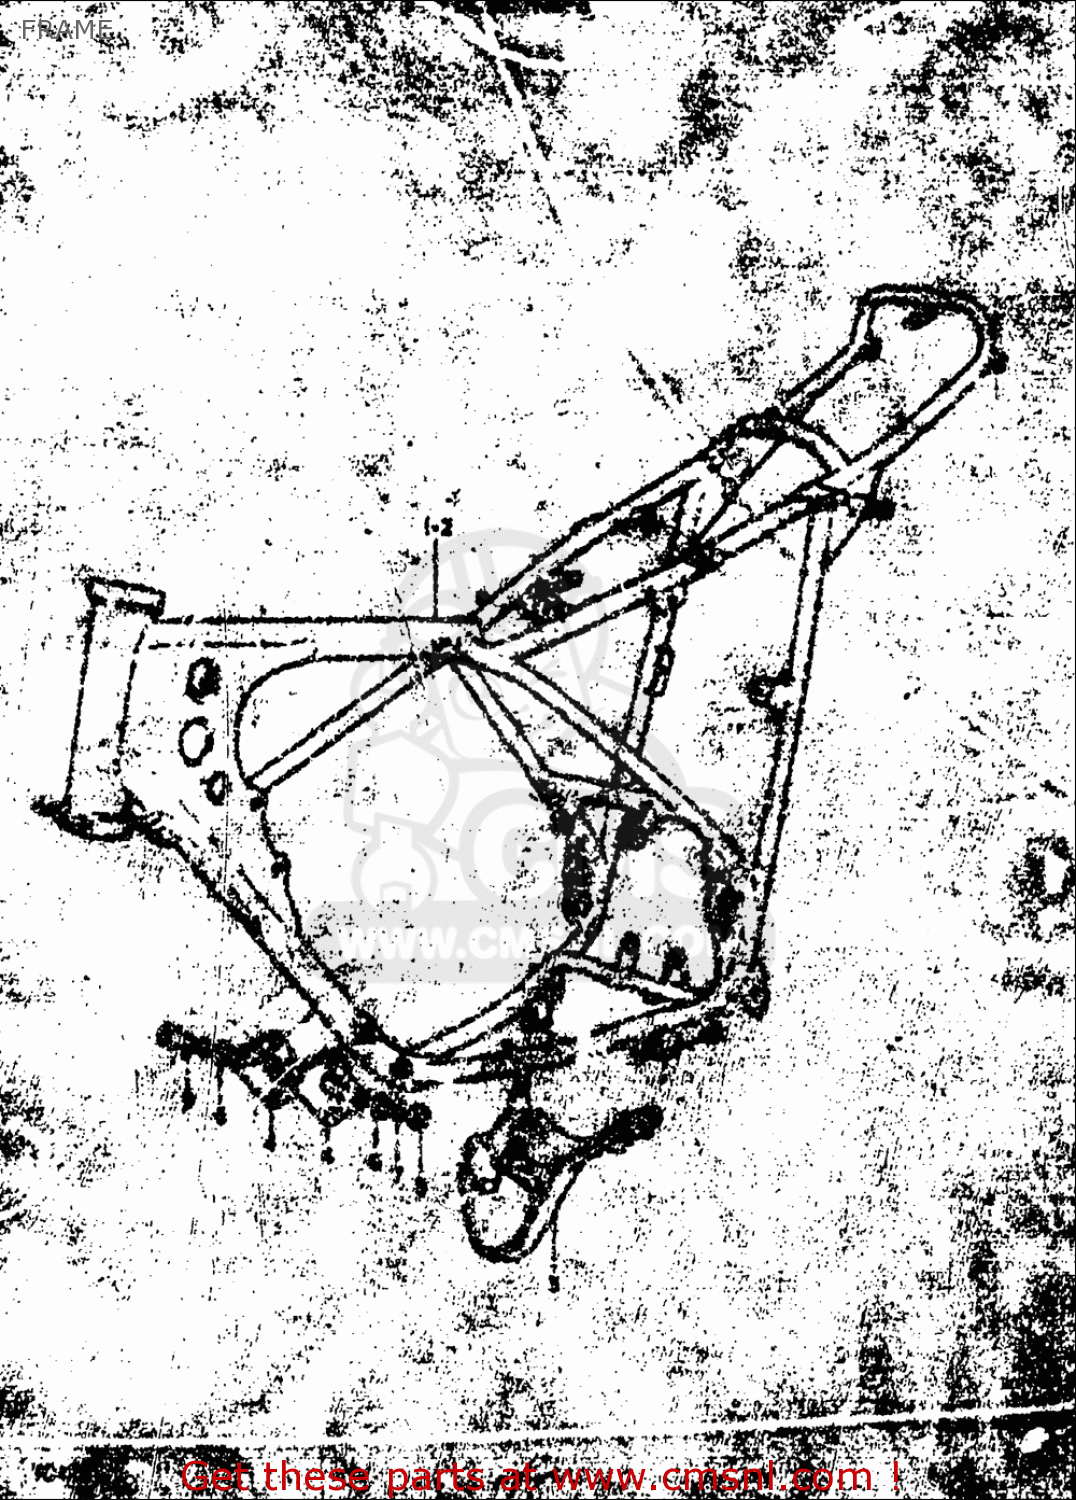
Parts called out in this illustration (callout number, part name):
5	BOLT
6	WASHER
7	WASHER,LOCK
8	NUT
